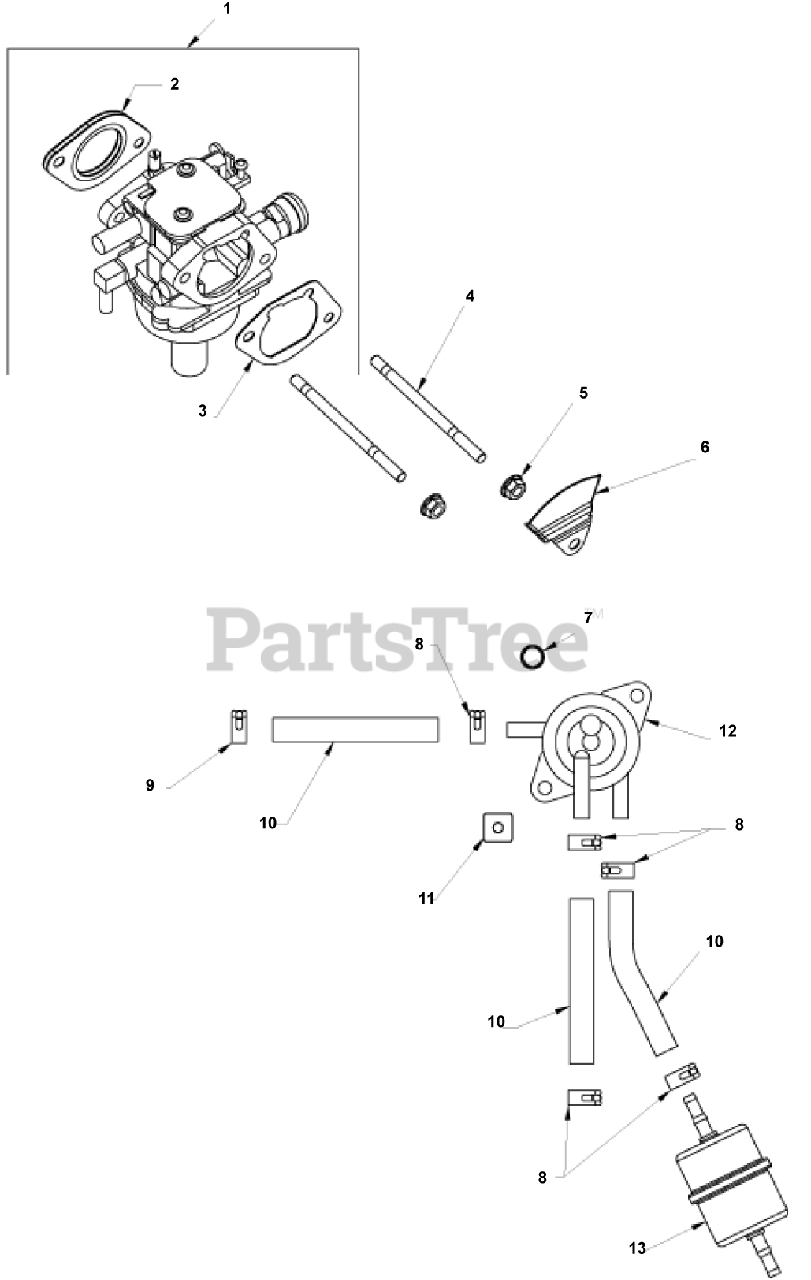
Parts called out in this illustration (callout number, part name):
1	KIT, CARBURETOR w/GASKETS
2	GASKET, CARBURETOR
3	GASKET, AIR CLEANER BASE
4	STUD,M6X1.0X96
5	NUT, FLG M6X1.0
6	BAFFLE, SPIT-BACK CUP-USE 24 063 105-S
7	SCREW, TAP M6X1.7X18
8	CLAMP, HOSE (KM)-USE 25 237 31-S
9	CLAMP, HOSE 1/2" USE 25 237 14-S
10	HOSE,LW PERM.FUEL 24.00"-USE 25 111 81-S
11	NUT, PLASTIC - BLACK
12	PUMP, FUEL
13	FILTER, FUEL
